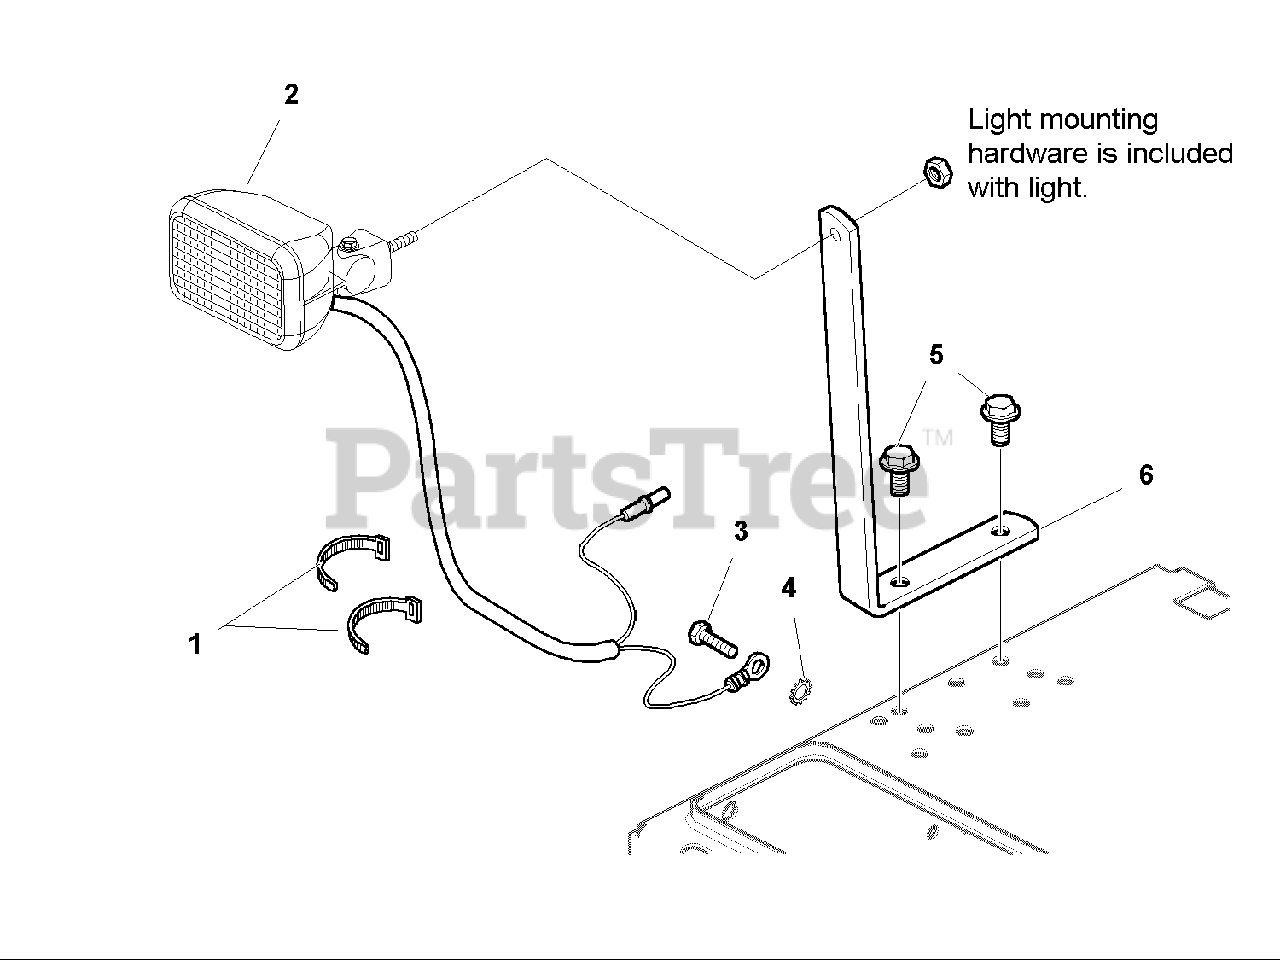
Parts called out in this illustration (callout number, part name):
2	LIGHT & COVER ASSEMBLY
3	CAPSCREW, Hex Head, 1/4-20 x 1/2
4	LOCK WASHER, External Tooth, 1/4
5	CAPSCREW, Hex Head Taptite, 3/8-16 x 3/4
